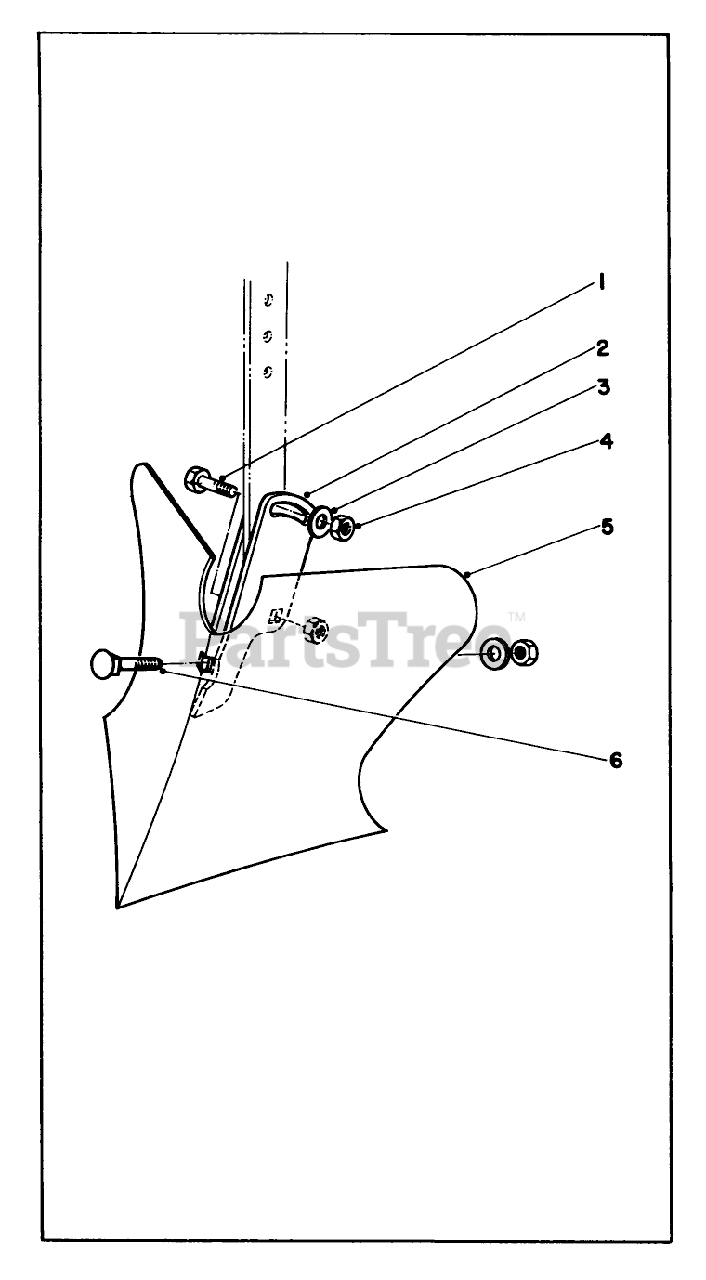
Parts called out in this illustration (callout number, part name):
1	SCREW-HH
2	Clamp
3	WASHER-FLAT
4	NUT-HEX
5	Shovel
6	Carriage Bolt
